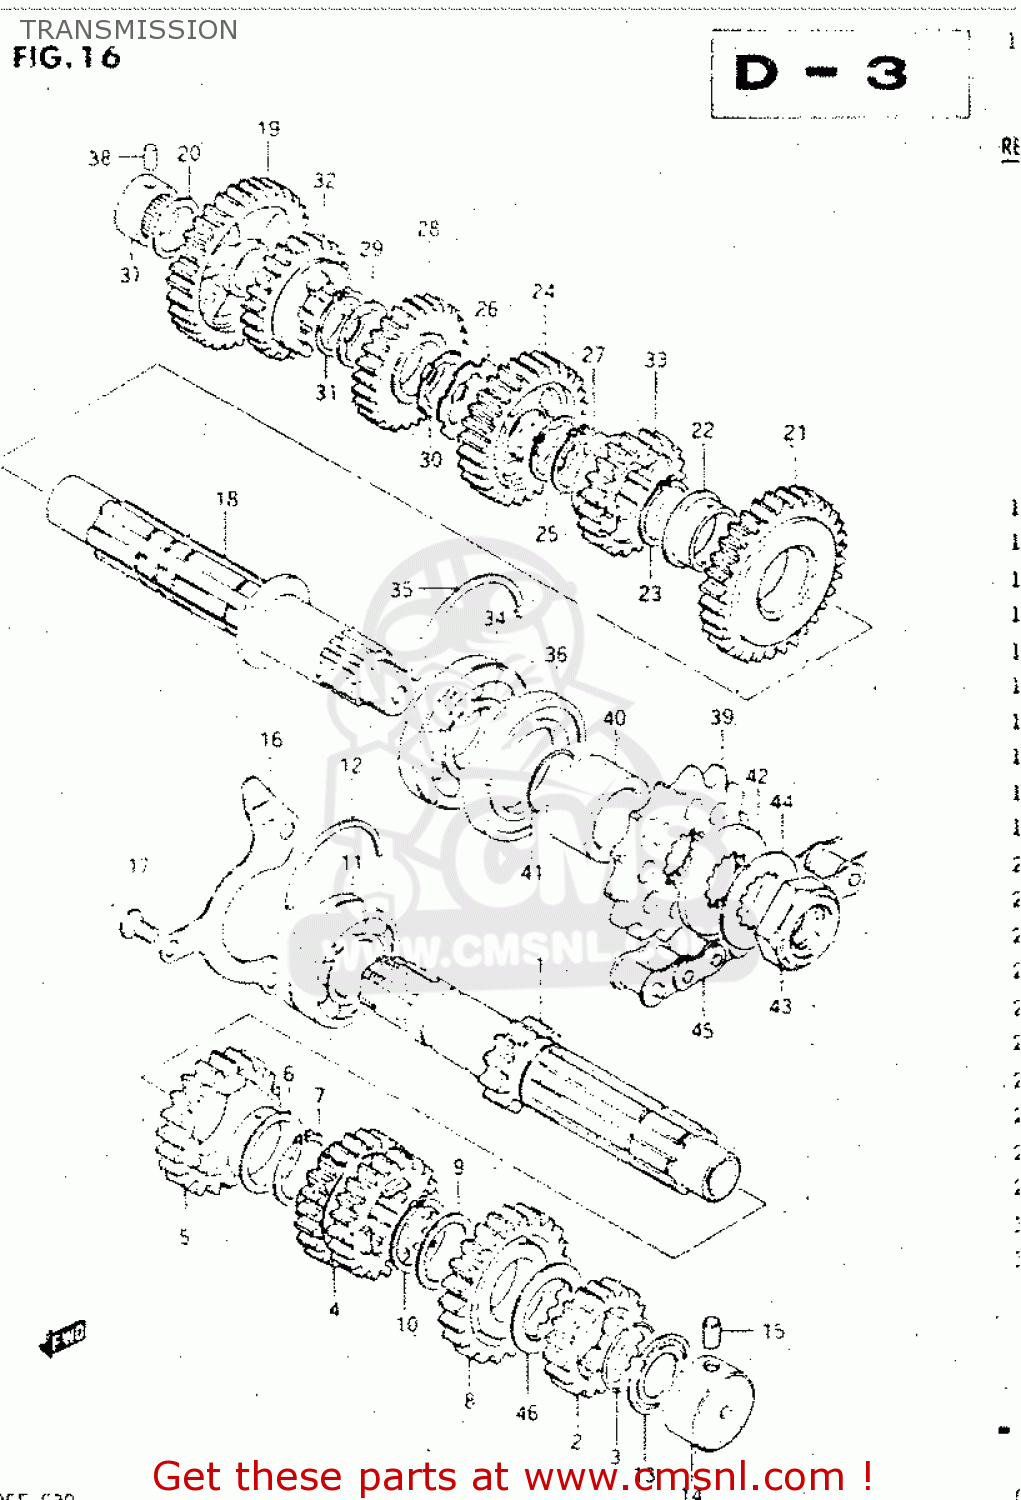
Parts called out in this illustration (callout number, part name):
1	SHAFT,COUNTER
2	GEAR,SECOND DRIVE
3	RING,SNAP
4	GEAR,THIRD/FOURTH DRIVE
5	GEAR,FIFTH DRIVE
6	BUSHING
7	RING,SNAP
8	GEAR,SIXTH DRIVE
9	WASHER,LOCK
10	RING,SNAP
11	BEARING(25X52X19.6)
12	C RING
13	SEAL,OIL(20X31.2X2.7)
14	BEARING(20X34X17.5)
15	PIN
16	PLATE,COUNTERSHAFT BEARING
17	SCREW
18	SHAFT,DRIVE
19	GEAR,FIRST DRIVEN
20	WASHER
21	GEAR,SECOND DRIVEN
22	BUSHING
23	RING,SNAP
24	GEAR,3RD DRIVEN
25	WASHER,LOCK
26	WASHER,LOCK
27	RING,SNAP
28	GEAR,FOURTH DRIVEN
29	WASHER,LOCK
30	WASHER
31	RING,SNAP
32	GEAR,FIFTH DRIVEN
33	GEAR,SIXTH DRIVEN
34	BALL BEARING 25X62X17
35	C-RING
36	SEAL,OIL(33X62X7)
37	BEARING(20X34X20)
38	PIN
39	SPROCKET,ENGINE
40	SPACER (25X33X20.1)
41	O RING(D:1,ID:24.5)
42	SPACER
43	NUT
44	WASHER
45	CHAIN, DRIVE (114LE)
46	SHIM
